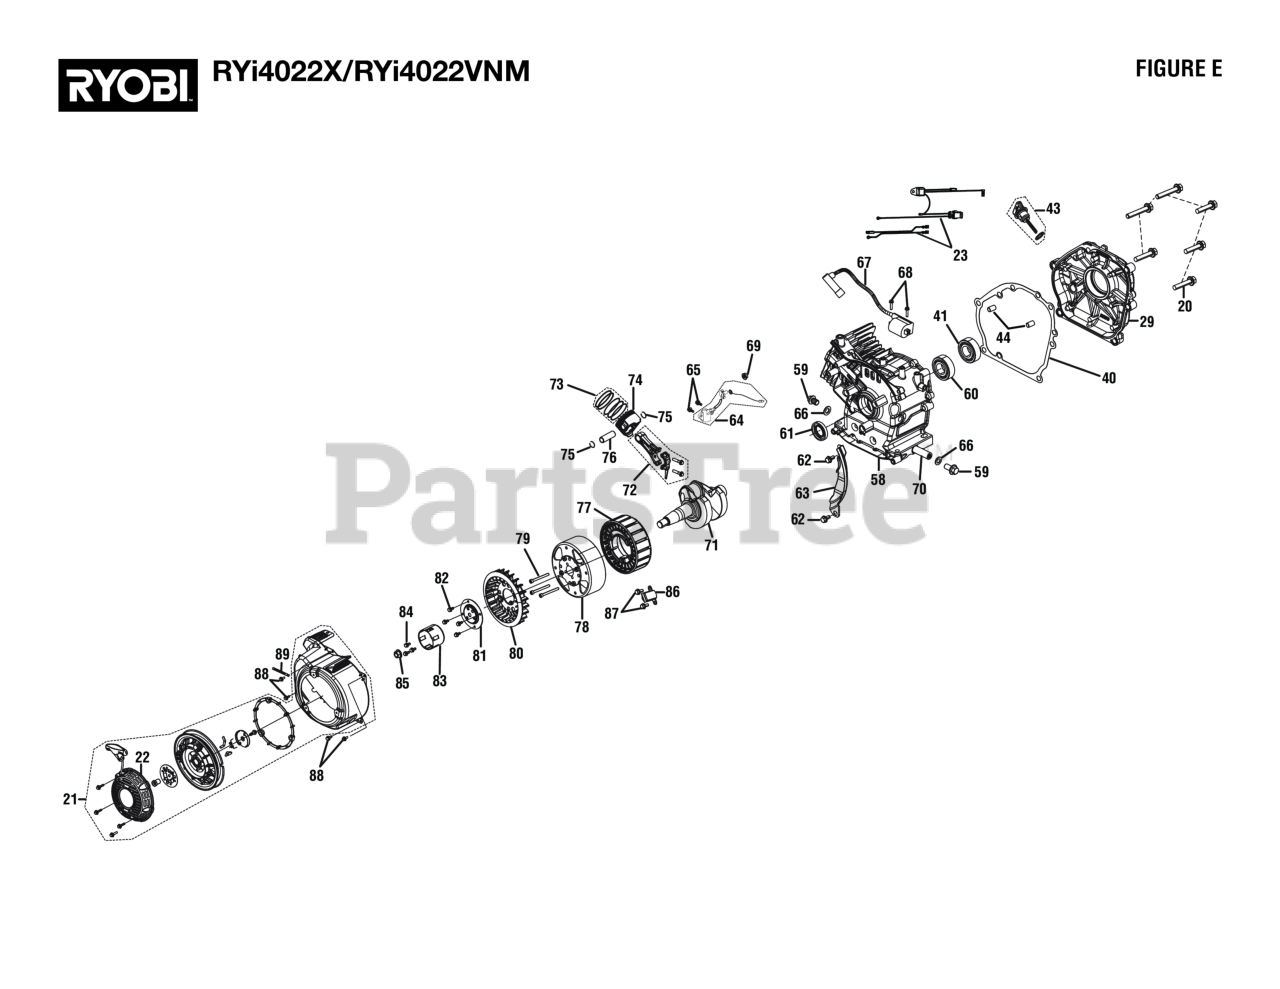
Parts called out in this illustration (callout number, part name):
21	Recoil Starter Assembly
22	Engine Recoil Cover
23	Ignition Wire Harness
29	Crankcase Cover
40	Crankcase Gasket
41	Ball Bearing
43	Oil Dipstick Assembly
58	Crankcase Assembly
59	Drain Plug Bolt
62	Bolt (need size)
64	Engine Oil Sensor
71	Crankshaft Assembly
73	Piston Ring Assembly
74	Piston Assembly
75	Piston Pin Clip
81	Starter Cup Seat
82	Bolt (need size)
84	Bolt
86	Trigger Assembly
88	Bolt (need size)
